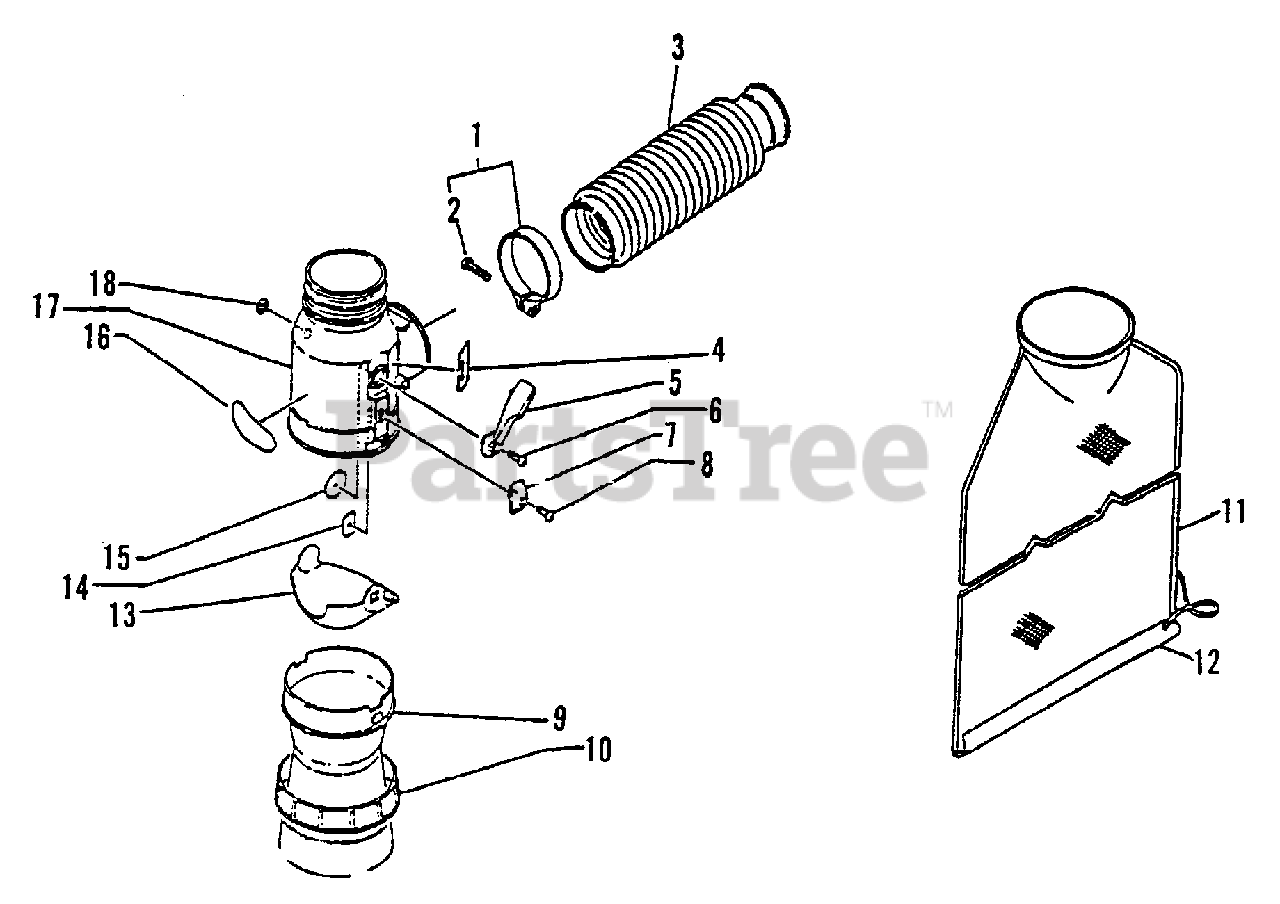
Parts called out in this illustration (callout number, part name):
1	CLAMP KIT
2	SCREW 5×25
3	TUBE, FLEXIBLE
6	SCREW 5×14
8	SCREW 4×14
9	CONNECTOR
11	BAG, VACUUM
12	CLIP, VACUUM BAG
16	LABEL - ECHO
17	TUBE, SUCTION
18	RING, RETAINING - 8
